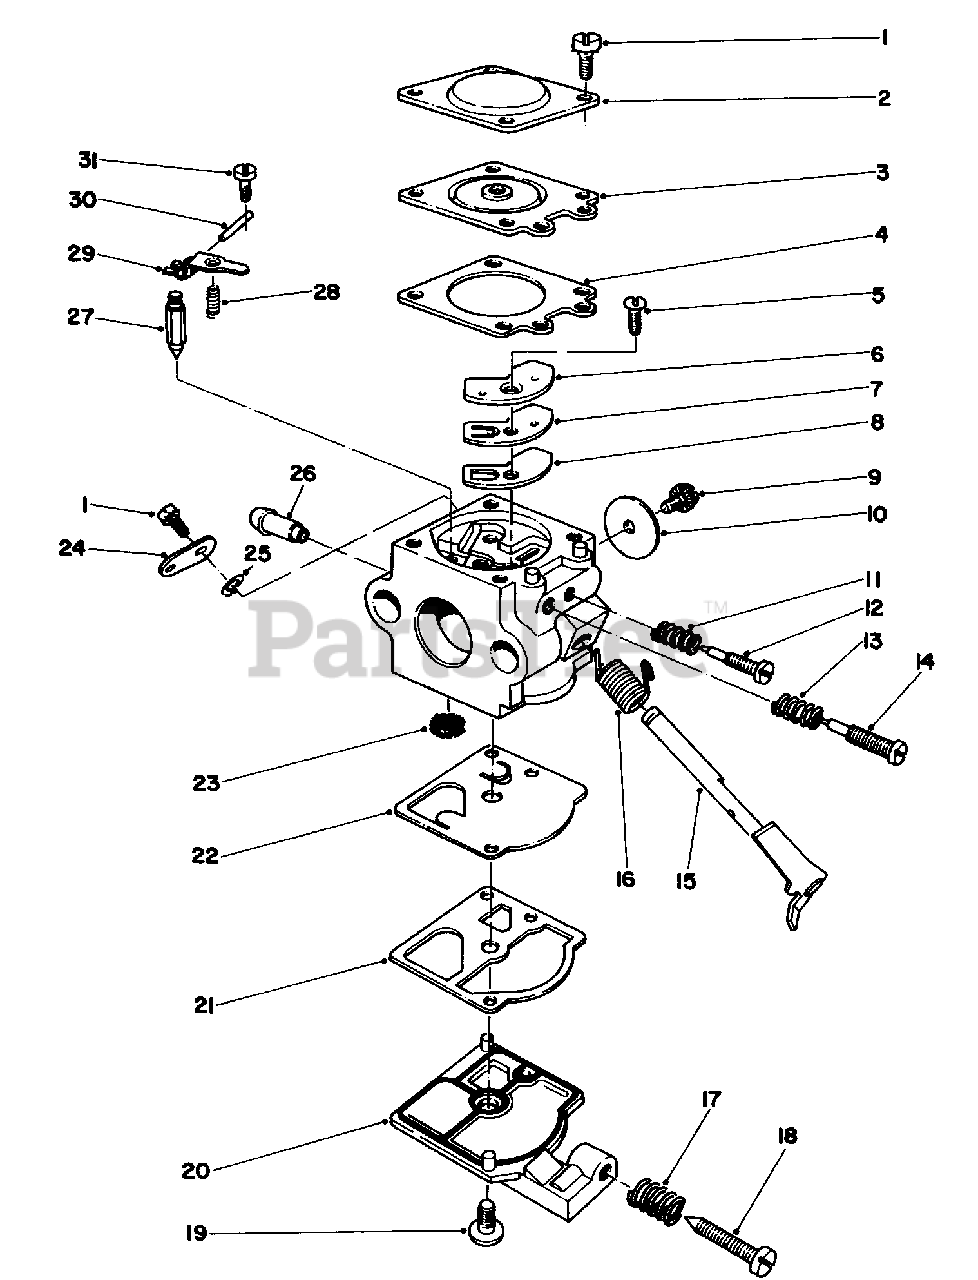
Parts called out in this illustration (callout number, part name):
1	Screw-Metering Cover & Throttle Lever
2	Cover-Metering Diaphragm
3	Diaphragm Assembly-Metering
4	Gasket-Metering Diaphragm
5	Screw-Circuit Plate
6	Plate Assembly-Circuit
7	Diaphragm-Circuit Check Valve
8	Gasket-Circuit Plate
9	Screw-Throttle Valve
10	Valve-Throttle
11	Spring-Needle (Idle)
12	Needle-Idle
13	Spring-Needle (Hi)
14	Needle Hi Speed
15	Shaft Assembly-Throttle
16	Spring-Throttle Lever
17	Spring-Idle Screw
18	Screw-Idle Adjust
19	Screw-Pump Cover
20	Cover-Fuel Pump
21	Gasket-Fuel Pump
22	Diaphragm-Fuel Pump
23	Screen-Fuel Inlet
24	Lever-Throttle
25	Ring-Throttle Retainer
26	Fitting Fuel Inlet
27	Valve-Inlet Needle
28	Spring-Metering Lever
29	Lever-Metering
30	Pin-Metering Lever
31	Screw-Metering Pin
